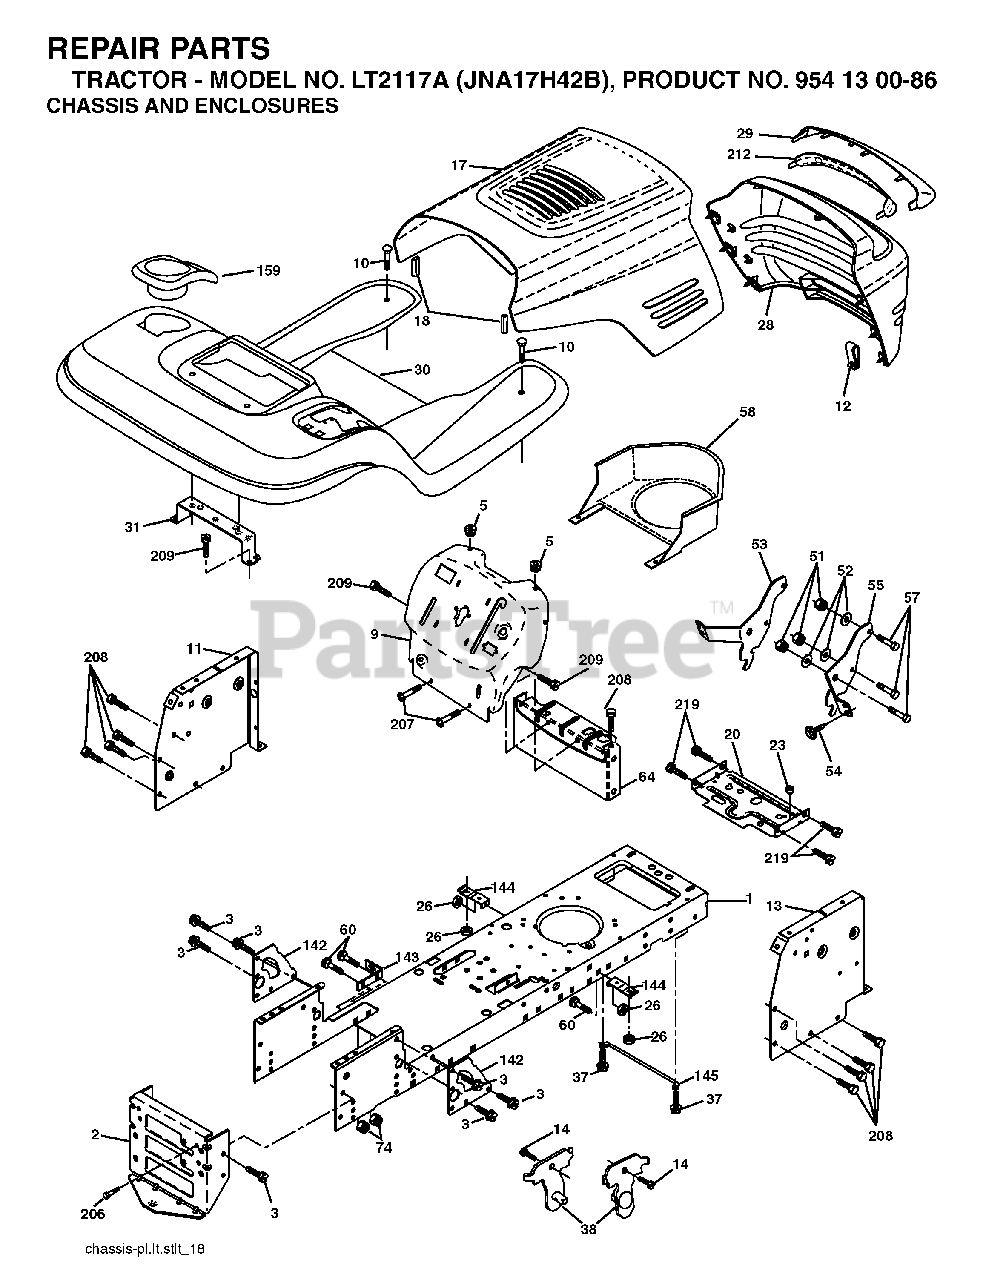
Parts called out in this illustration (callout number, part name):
1	CHASSIS STAMPING
2	DRAWBAR, 12GA
3	SCREW 3/8-16X3/4
5	BUMPER.RUBBER.HOOD
10	BOLT D
11	PANEL.DASH.LH.LTX
13	PANEL ASM, DASH RH
18	BUMPER.HOOD.LARGE.1.75"
20	PLATE MTG.BATTERY/FUEL TANK
23	GROMMET T
26	NUT
28	GRILL/LENS ASM.
38	BRACKET.ASM.PIVOT.MOWER.REAR
51	LOCKNUT
53	BRACKET.GRILLE.LH
57	BOLT
58	AIR DUCT P/L/LT
64	DASH LOWER
74	LOCKNUT
142	PLATE REINFORCEMENT
143	BRACKET, SWAY BAR
144	BRKT, FOOT REST
145	ROD PIVOT CHASSIS/HOOD
206	SHOULDER BOLT 5/16-18TT
207	SCREW, 5/16-18 X 1/2
208	SCREW 3/8-16X1/2
209	SCREW, 3/8-16X3/4
219	SCREW
